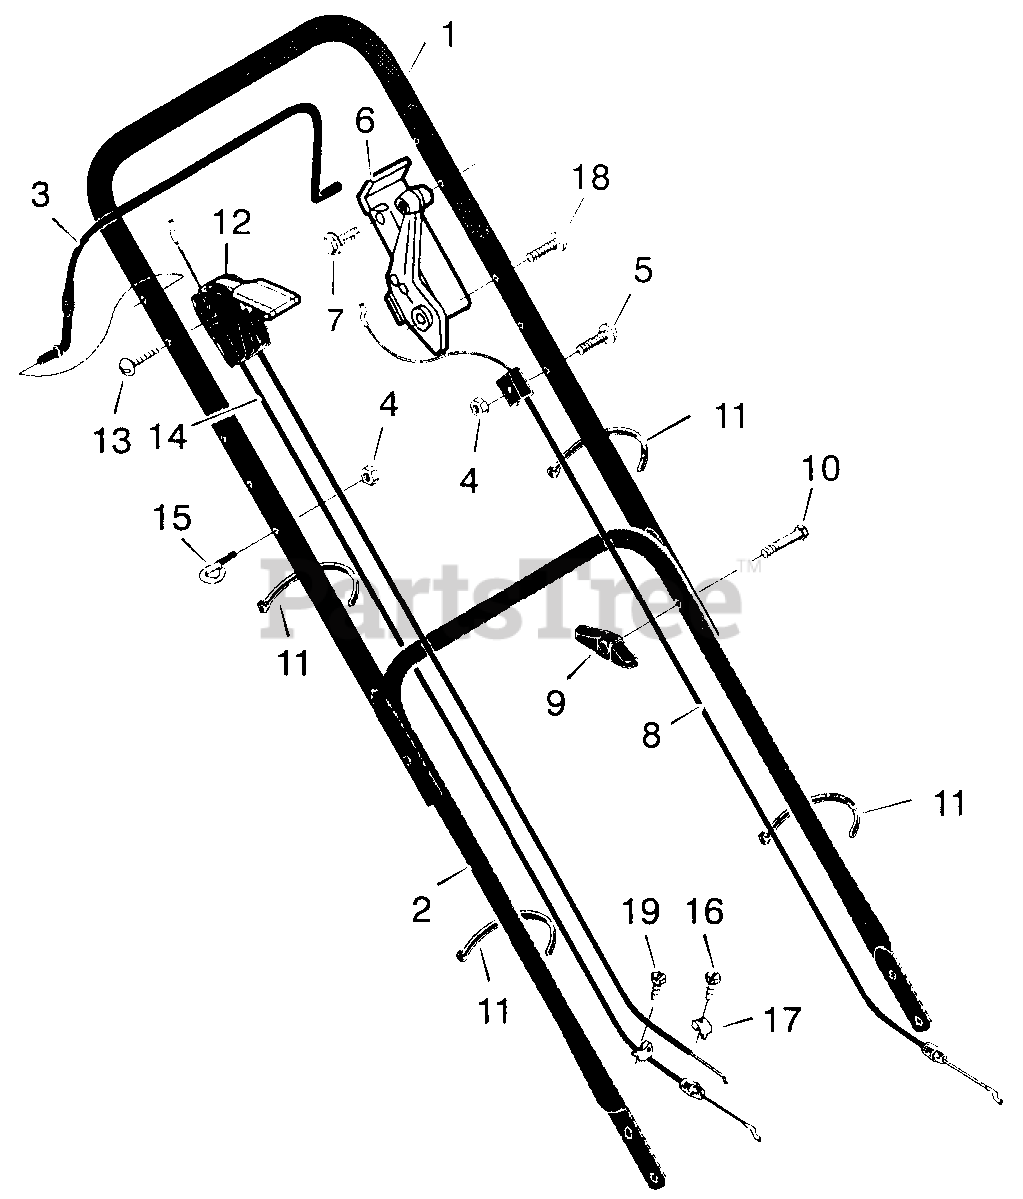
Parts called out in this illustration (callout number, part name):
1	Handle, Upper - (Black)
2	Handle, Lower (Black)
3	Lever, Stop
4	Locknut
6	Drive Control
8	Cable, Drive
9	Knob
11	Fastener, Cable
12	Throttle Control
14	Engine Stop Cable
15	GUIDE, ROPE
16	Screw
17	Clamp
